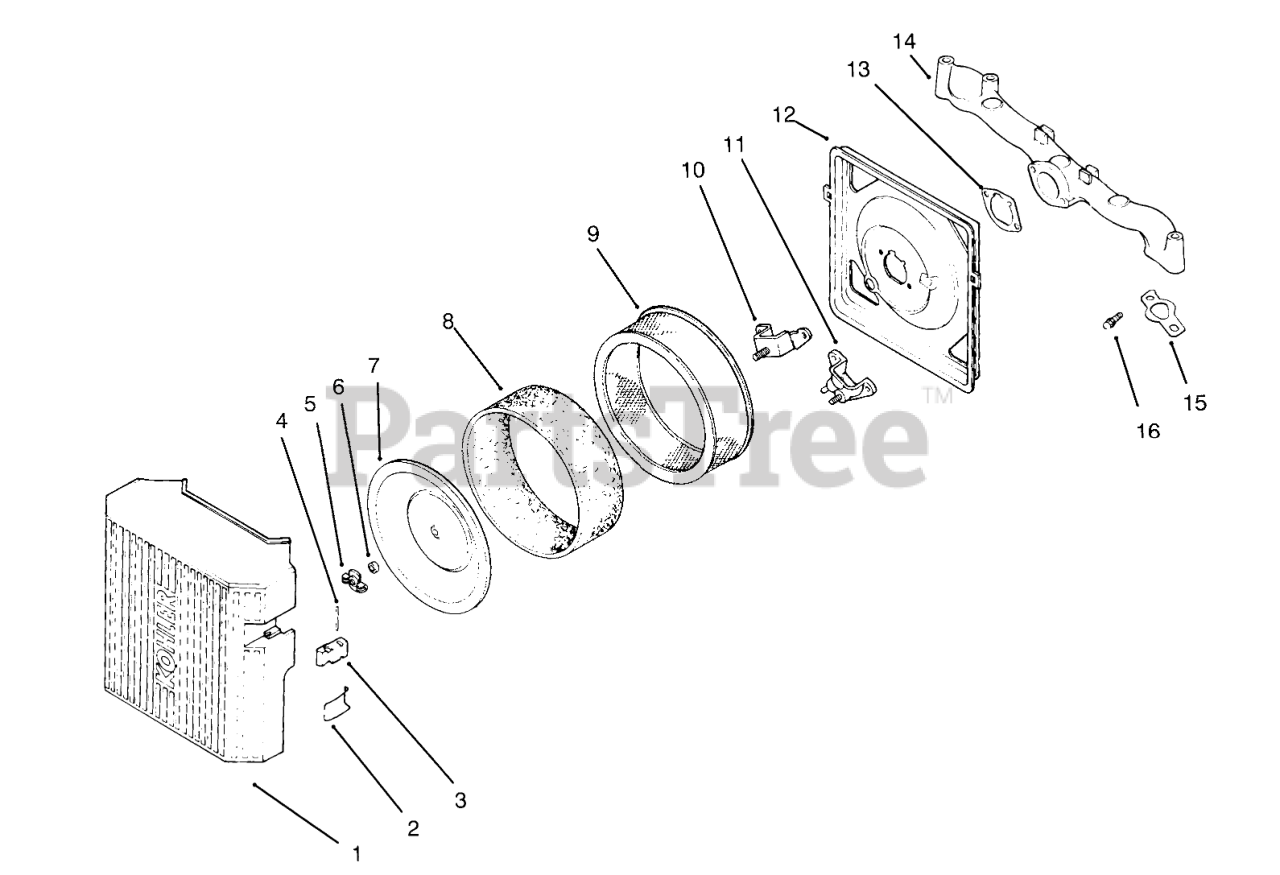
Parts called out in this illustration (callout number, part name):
1	Kit-A/C Cover INCL 2-4 (Only On: 72103)
2	Spring-Latch (Only On: 72103)
3	Latch-Lever (Only On: 72103)
4	Pin-Latch Lever (Only On: 72103)
5	Nut-Wing (Only On: 72103)
6	Seal-Air Intake (Only On: 72103)
7	Cover-Inner Air Cleaner (Only On: 72103)
8	Element-Precleaner (Only On: 72103)
9	Element-Air Cleaner (Only On: 72103)
10	Cup-Fuel Spitback (Only On: 72103)
11	Gasket-Fuel Spitback Cup (Only On: 72103)
12	Base-Air Cleaner (Only On: 72103)
13	Gasket-A/C Base (Only On: 72103)
14	Manifold-Intake (Only On: 72103)
15	Gasket-Intake Manifold (Only On: 72103)
16	Screw M6x1.0x18 (Only On: 72103)
